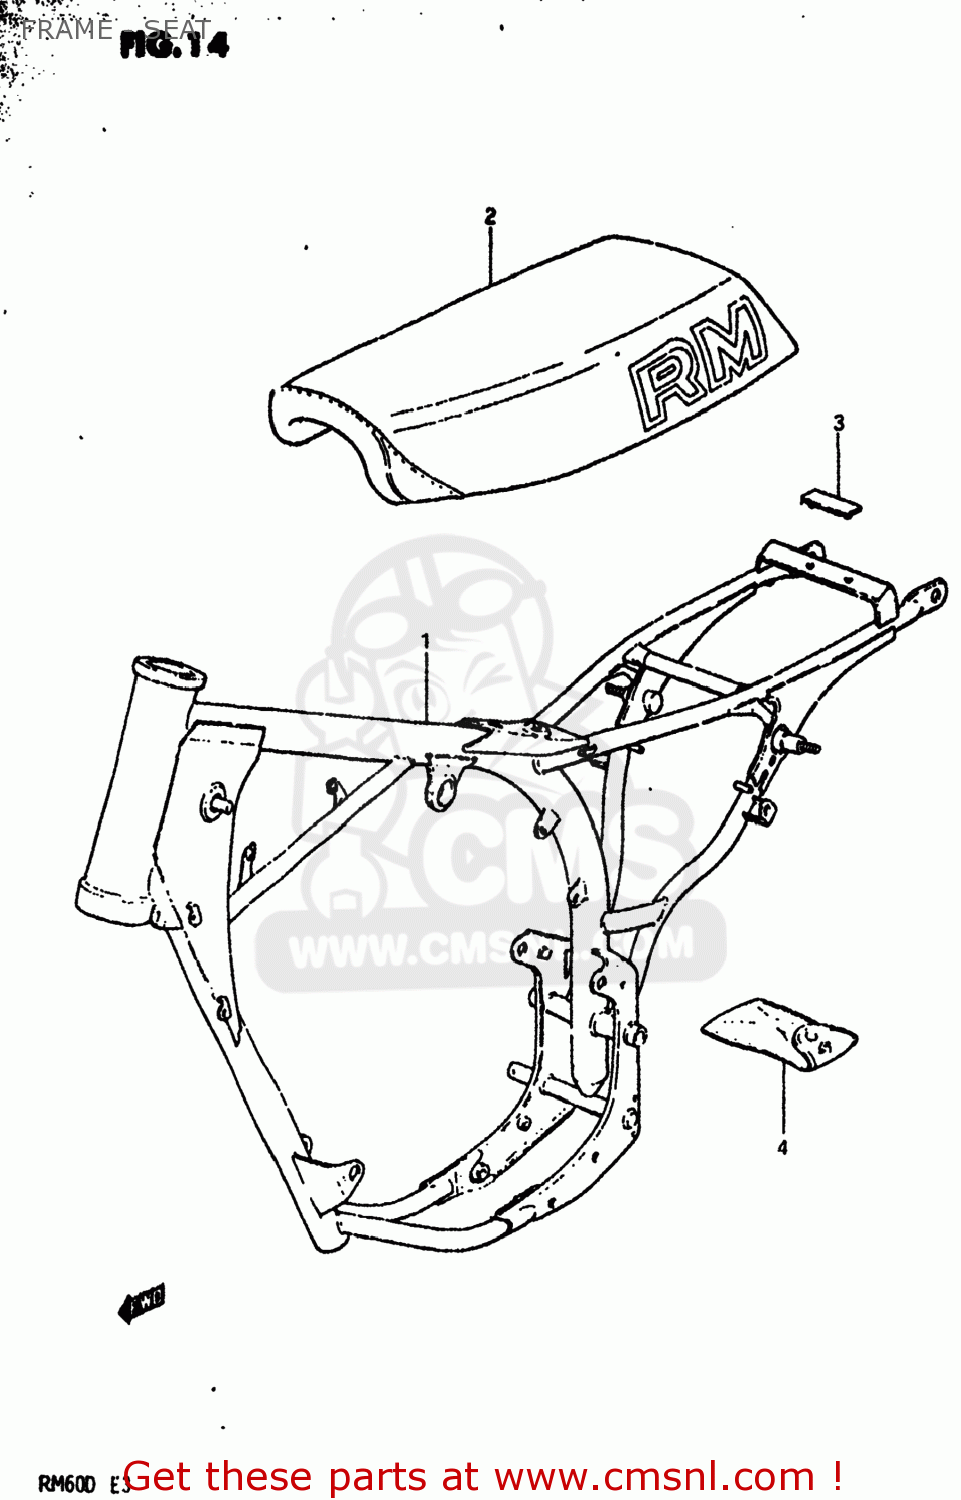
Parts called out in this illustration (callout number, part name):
1	FRAME
2	SEAT ASSEMBLY
4	TOOL SET
